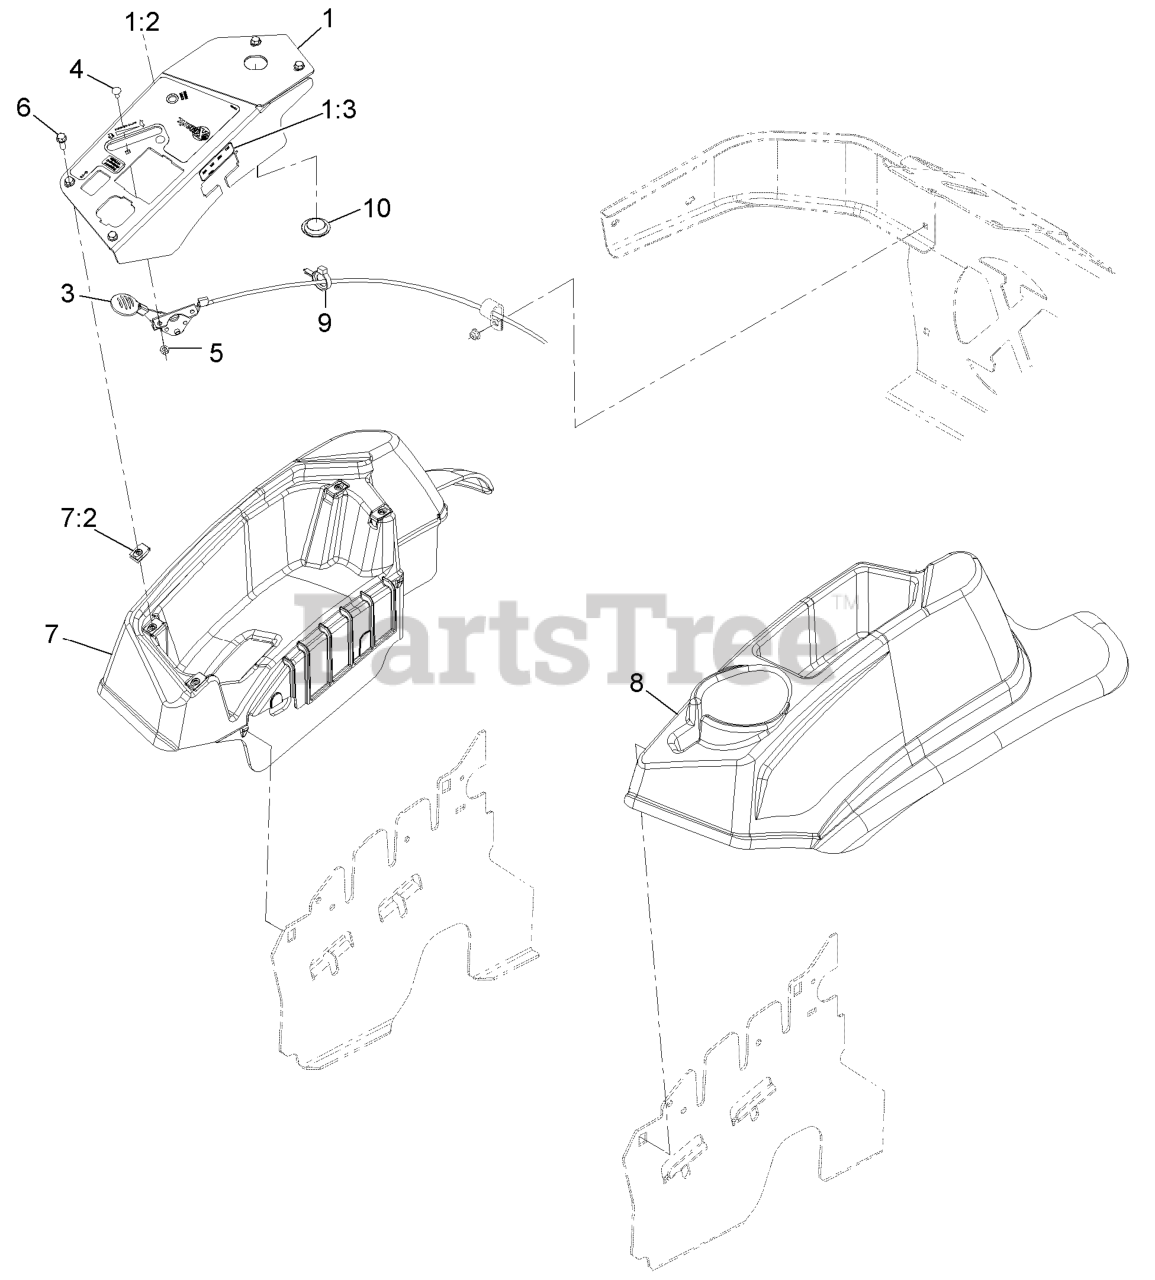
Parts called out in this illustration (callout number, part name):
1	ASM,CONTROL PANEL W/DECAL
1:2	DECAL,CONTROL PANEL EFI
1:3	DECAL-FUSE
3	ASM,THROTTLE CABLE
4	BOLT-CARR
5	NUT-LOCK, NI
6	SCREW-HWH
7	CONSOLE,RH AS ASM
7:2	Nut-Retainer-Panel 1/4-20
8	CONSOLE, LH AS
9	CLAMP-HOSE
10	PLUG-PLASTIC
